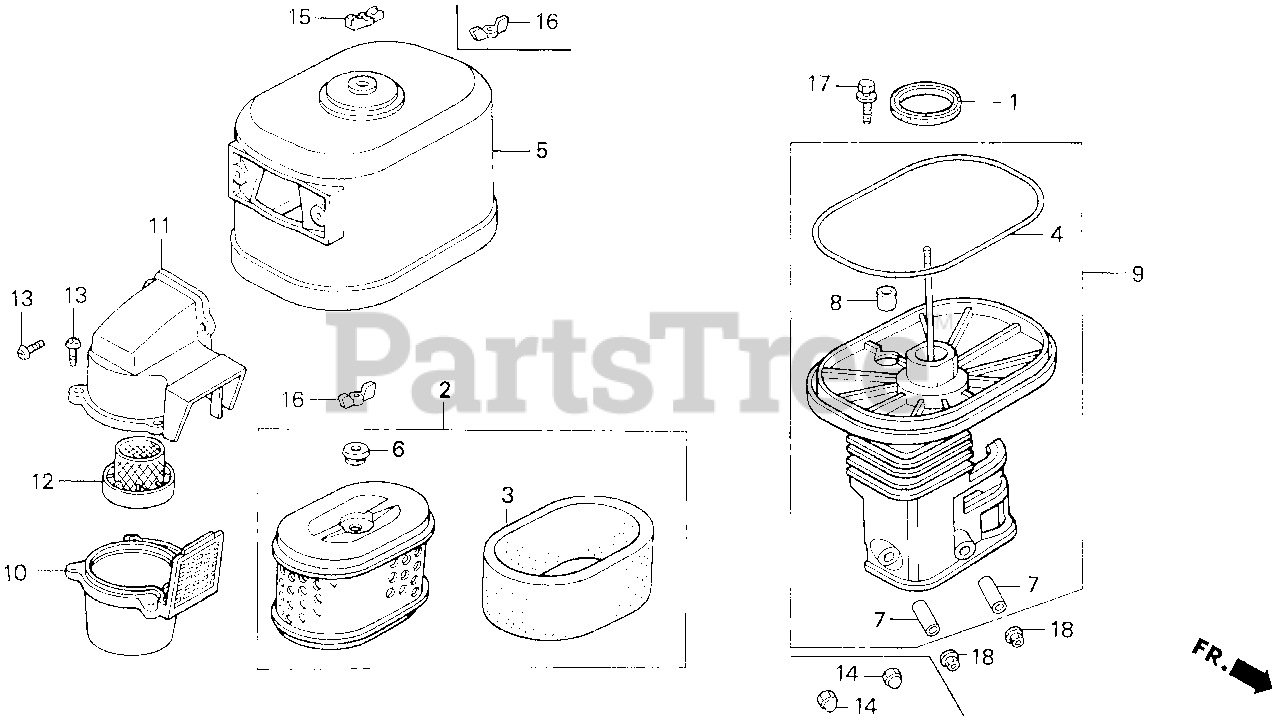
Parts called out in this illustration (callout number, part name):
1	GASKET, ELBOW
2	ELEMENT, AIR CLEANER
3	FILTER (OUTER)
4	SEAL, AIR CLEANER COVER
5	COVER, AIR CLEANER (CYCLONE)
6	GROMMET, AIR CLEANER
7	COLLAR, AIR CLEANER
8	COLLAR B, AIR CLEANER
9	ELBOW, AIR CLEANER
10	CASE, PRE AIR CLEANER
11	CAP, PRE AIR CLEANER
12	GUIDE, PRE AIR CLEANER
13	SCREW, PAN (5X16.5)
15	WINGNUT (6MM)
16	WINGNUT, TOOL BOX SETTING
17	BOLT-WASHER (6X20)
18	NUT, FLANGE (6MM)
